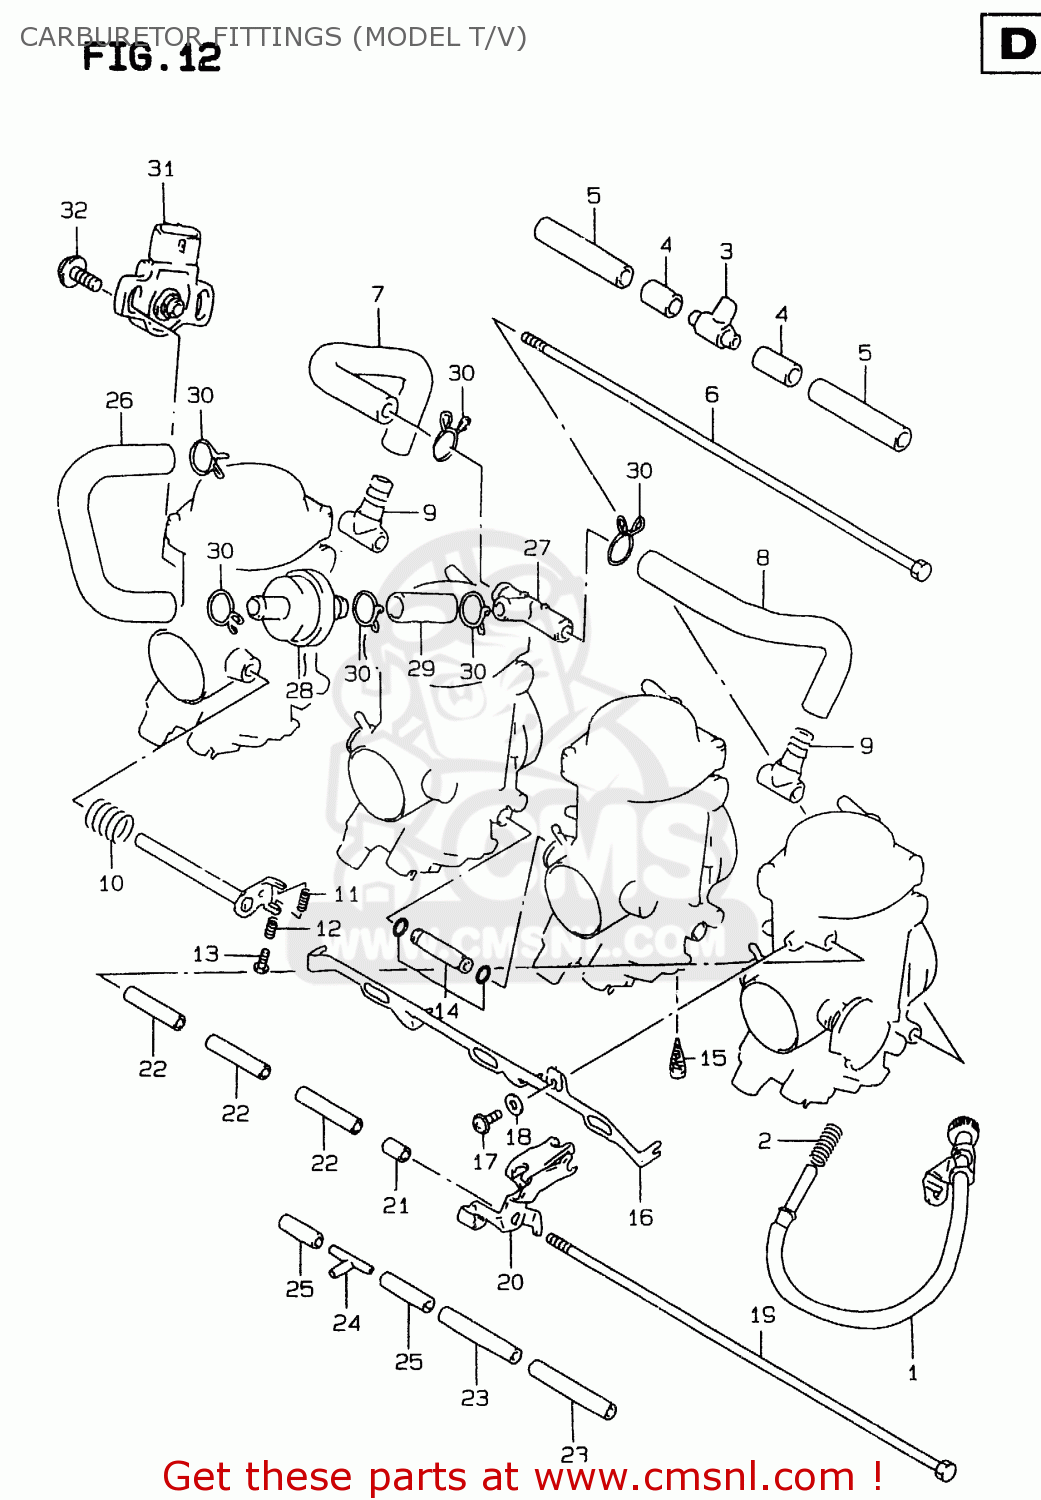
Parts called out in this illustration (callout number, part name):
1	ADJUSTER
2	SPRING
3	NIPPLE
4	HOSE
5	HOSE
6	BOLT
7	HOSE
8	HOSE
9	3 WAY
10	SPRING
11	SPRING,THROTTLE SCREW
12	SPRING
13	SCREW
14	NIPPLE,CARBURETOR
15	FILTER
16	LEVER,STARTER
17	SCREW
18	PACKING
19	BOLT
20	BRACKET
21	RING
22	PIPE
23	HOSE
24	3-WAY
25	HOSE
26	HOSE,AIR VENT(NO.1)
27	JOINT
28	FILTER,AIR VENT
29	HOSE(11X15X600)
30	CLIP
31	SENSOR ASSY,THROTTLE
32	SCREW, SENSOR
